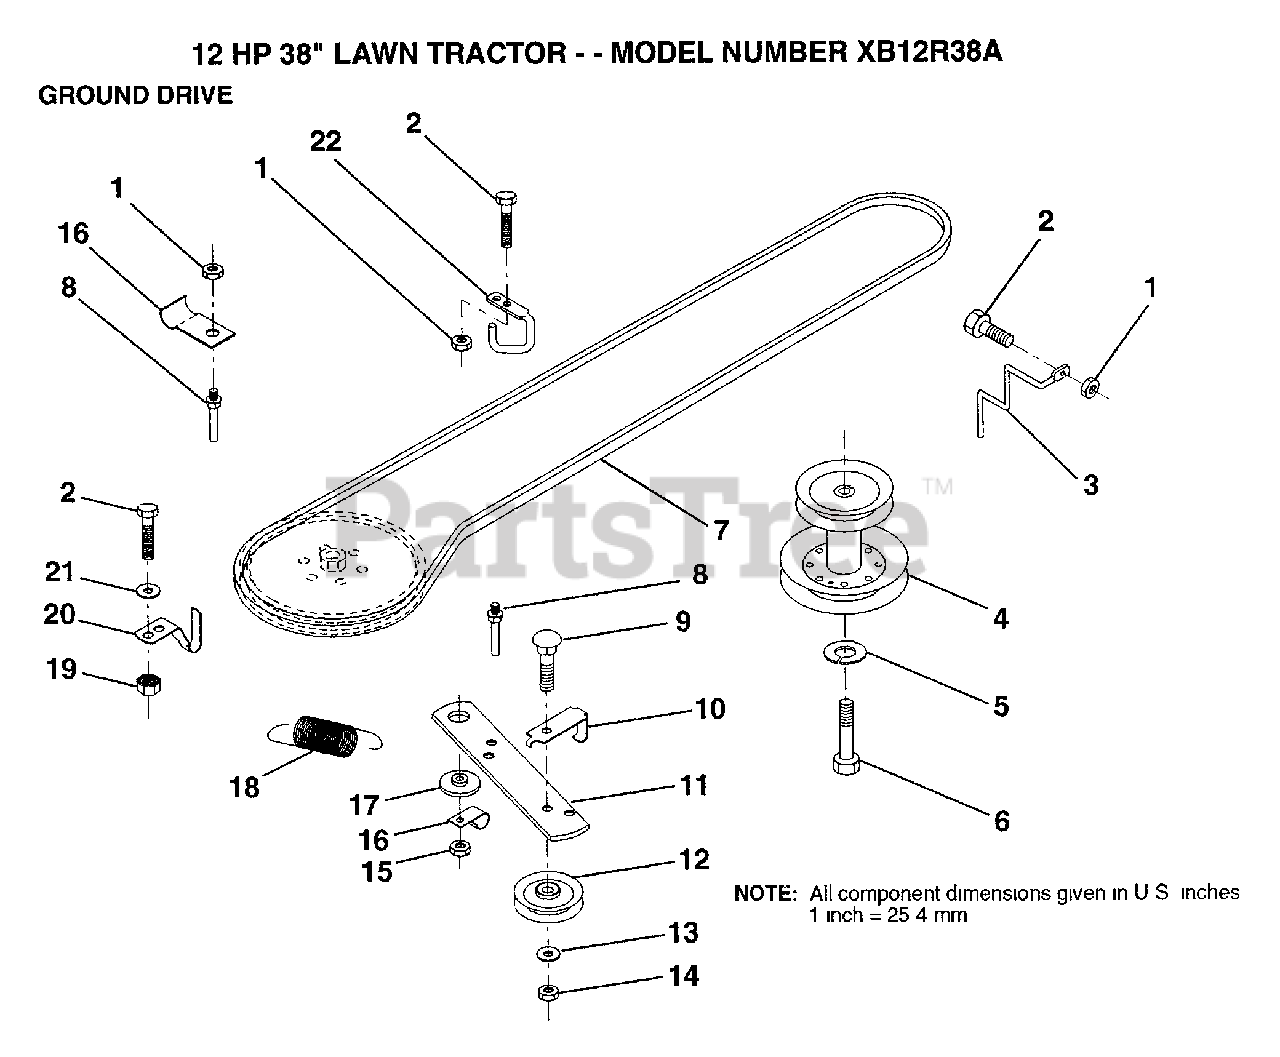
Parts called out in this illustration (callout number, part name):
2	BOLT
3	KEEPER MWR DR BLT
5	LOCKWASHER
6	BOLT
7	BELT
8	"KEEPER,DRIVE BELT"
9	BOLT
10	"KEEP,IDLER DR BEL"
13	WASHER
14	LOCKNUT
16	"CLIP,INSULATOR"
17	SPACER RETAINER
20	"KEEPER,DR BELT "
21	WASHER
22	"KEEPER,FRA DR BEL"
